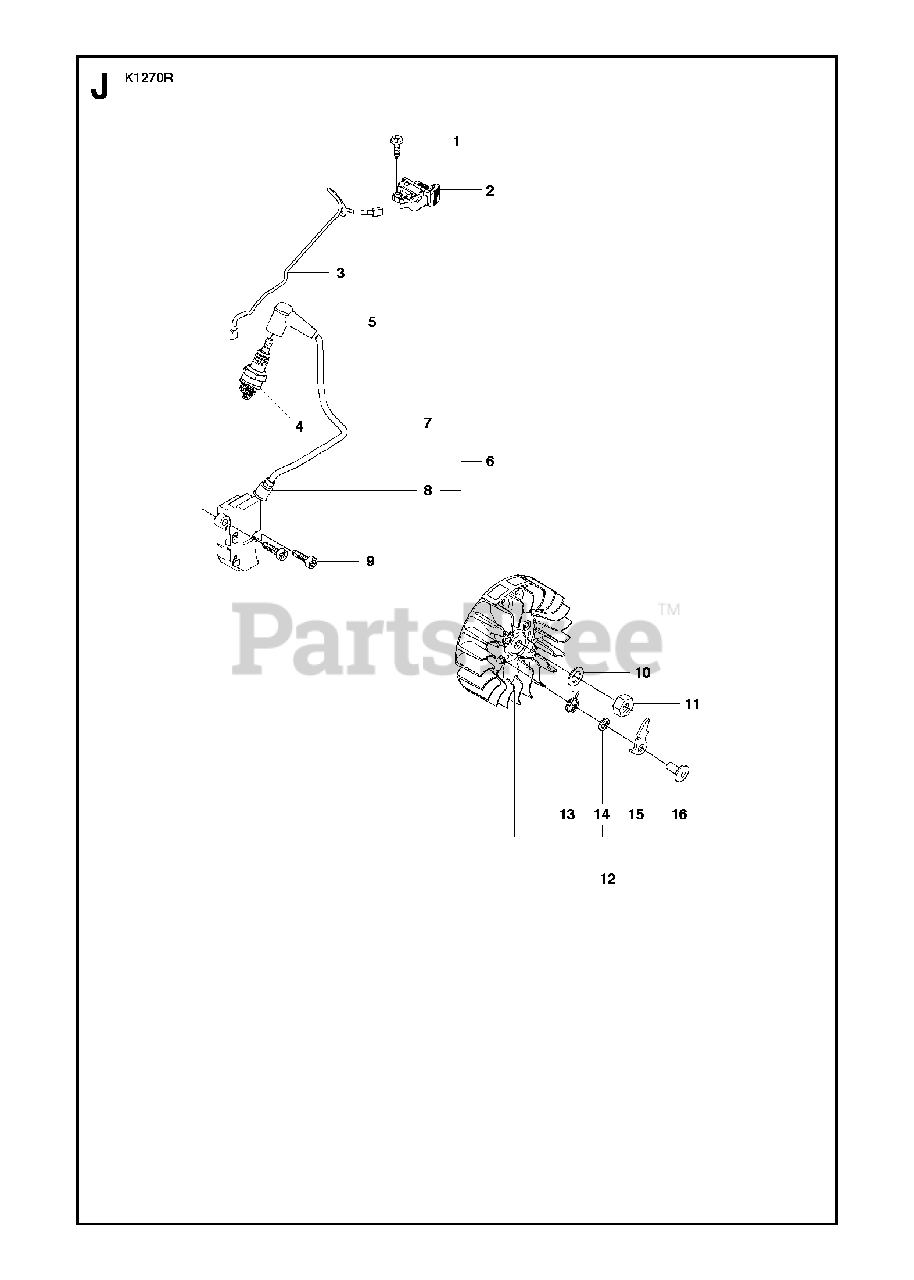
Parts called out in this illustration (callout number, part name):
1	SCREW CITXPANT
4	SPARK PLUGRCJ 6Y
5	SPARK PLUG CAP
6	IGNITION MODULEIncl. 7 - 8
7	IGNITION CABLE
9	SCREW ITXSCM
10	SPRING WASHER
12	FLYWHEEL ASSYIncl. 13 - 16
